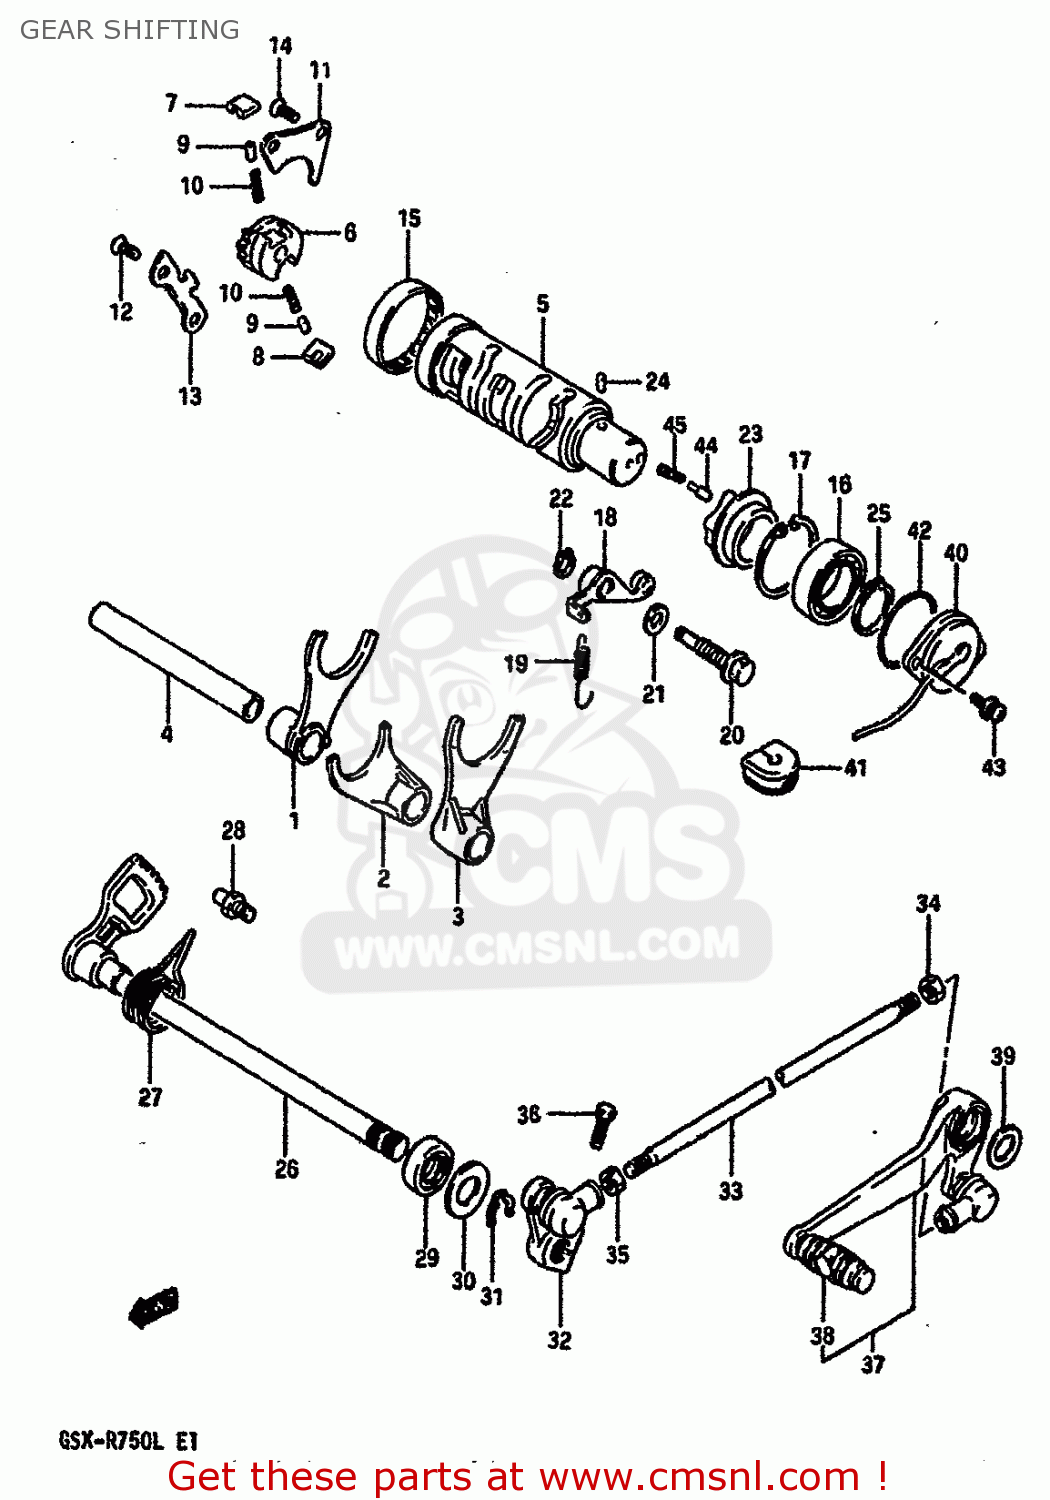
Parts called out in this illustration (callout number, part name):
1	FORK,GEAR SHIFT NO.1
2	FORK,GEAR SHIFT NO.2
3	FORK,GEAR SHIFT NO.3
4	SHAFT,GEAR SHIFT FORK(L:128)
5	CAM,GEAR SHIFT
6	GEAR,GEARSHIFT CAM DRIVE
7	PAWL,GEAR SHIFT NO.1
8	PAWL,GEAR SHIFT NO.2
9	PIN(5X8)
10	SPRING
11	LIFTER,GEAR SHIFT PAWL
12	SCREW
13	GUIDE,GEAR SHIFT CAM
14	SCREW
15	BEARING(43X49X12)
16	BALL BEARING
17	CIRCLIP,42MM
18	STOPPER,GEAR SHIFT CAM
19	SPRING
20	SHAFT,GEAR SHIFT CAM STOPPER
21	GASKET(10X14X3.6) (NAS)
22	CIRCLIP
23	PLATE,STOPPER
24	PIN 4X6
25	CIRCLIP,25MM
26	SHAFT,GEAR SHIFT
27	SPRING
28	STOPPER,GEAR SHIFT CAM
29	OIL SEAL
30	WASHER (12.5X27X1.6)
31	SPRING,RETAINER
32	ARM,GEAR SHIFT
33	ROD,GEAR SHIFT LINK
34	NUT
35	NUT 6MM
36	BOLT
37	LEVER ASSEMBLY,GEAR SHIFTING
38	RUBBER,GEAR SHIFT PEDAL
39	WASHER(18X24X1)
40	TERMINAL BASE ASSY,NEUTRAL
41	GROMMET,LEADWIRE
42	O RING(D:2.4,ID:36.5)
43	SCREW
44	PIN(5X15.5)
45	SPRING
